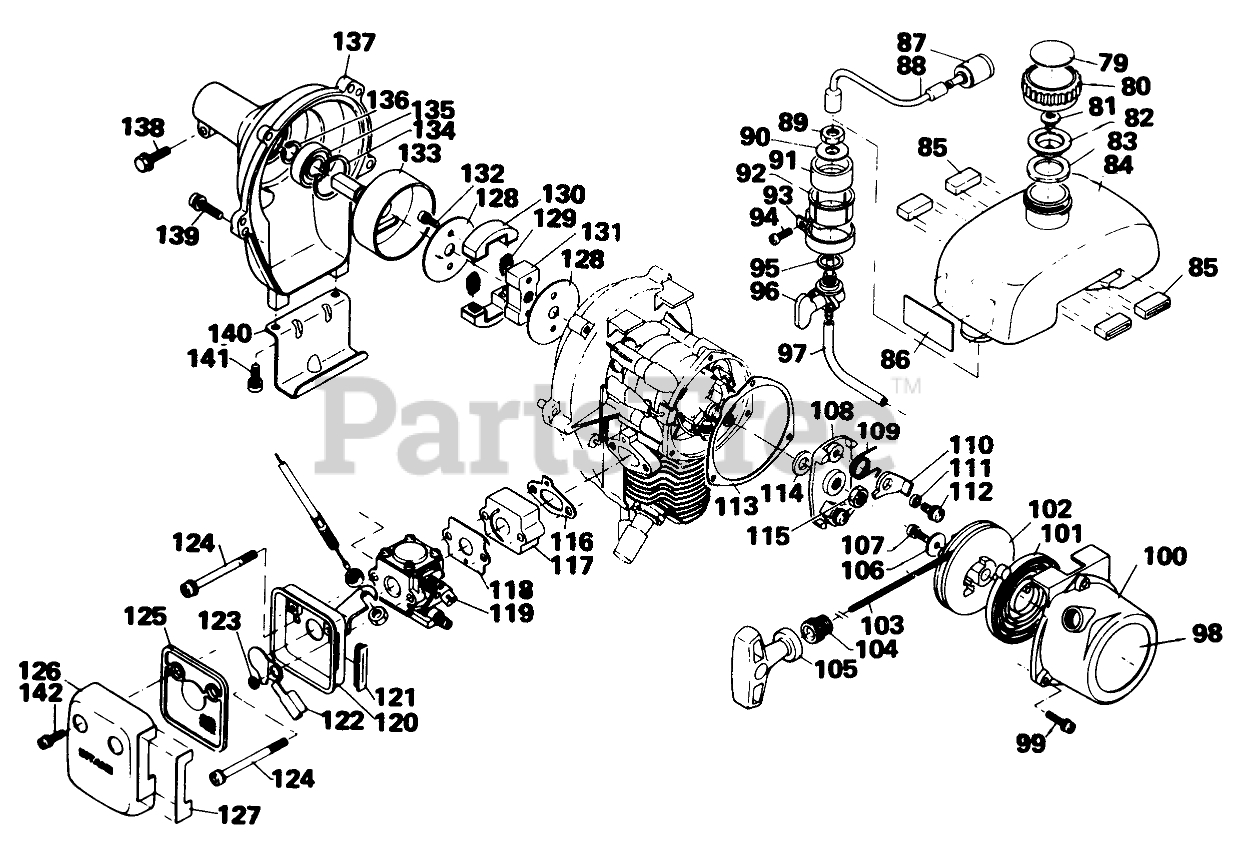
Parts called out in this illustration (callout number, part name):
79	Decal, Fuel
80	Cap-Fuel Tank
81	Check Valve
82	Holder, Check Valve
83	Gasket, Fuel Tank Cap
84	Fuel Tank
85	Cushion
86	Decal, Fuel Valve
87	Fuel Strainer
88	Fuel Pipe
90	WASHER
92	Collar
93	CLAMP
94	SCREW
95	GASKET
96	FUEL VALVE ASM
97	FUEL PIPE
98	Decal
99	Screw
100	Starter Case
101	REWIND SPRING
102	RECOIL DRUM
103	Rope-Starter
104	Rope Guide
105	Starter Handle
106	Washer
107	Screw
108	PAWL CATCHER
109	Ratchet Spring
110	RATCHET
111	RATCHET SPACER
112	SCREW
113	STARTER CASE GASKET
114	Spacer
115	Nut L.H.
116	GASKET
117	Insulator
118	GASKET
119	Carburetor Assy.
120	Case, Air Cleaner
121	GROMMET
122	Choke Shutter
123	CHOKE SHUTTER SPACER
124	SCREW
125	AIR FILTER
126	Cover, Air Filter
127	Decal, Caution
128	Side Plate, Clutch
129	Clutch Spring
130	CLUTCH SHOE
131	Clutch Boss
132	Screw
133	Clutch Drum
134	Circlip
135	Bearing
136	Circlip
137	Fan Cover
139	Screw
140	Bracket
141	Screw
142	Screw
